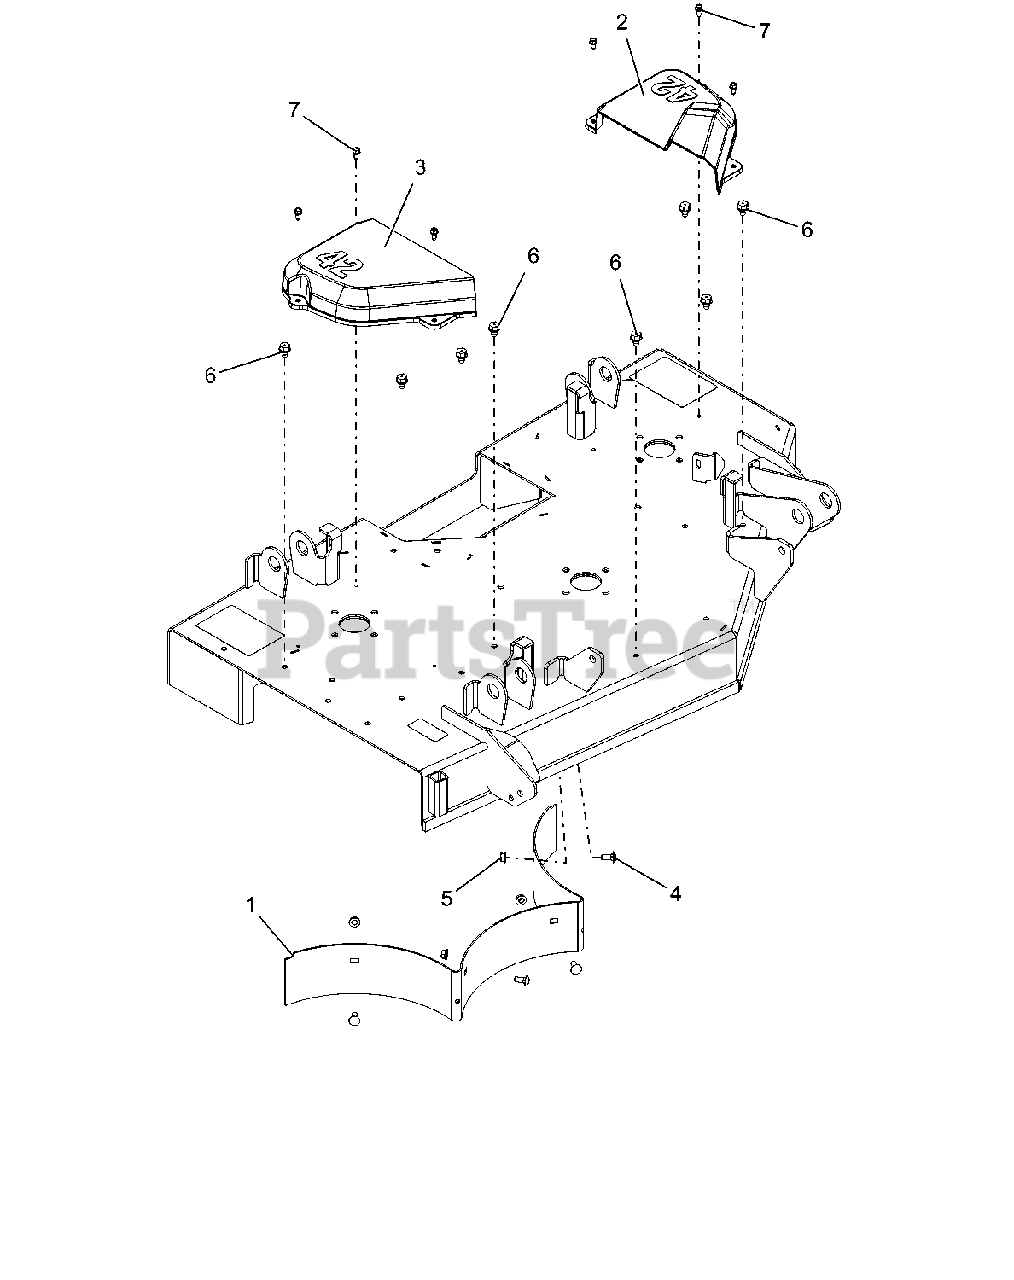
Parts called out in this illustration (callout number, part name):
1	BAFFLE, REAR 42
2	COVER, BELT 42" LH
3	COVER, BELT 42" RH
4	@BLT-RDHDSQNK .31-18X.75 G5YZ
5	@NUT-LK-TOP-FLG .31-18 YWZC
6	@SCR-TAP .38-16X.50 HWH TR YWZ
7	SCR-TAP .25-20X.50 HWH TR YWZ
